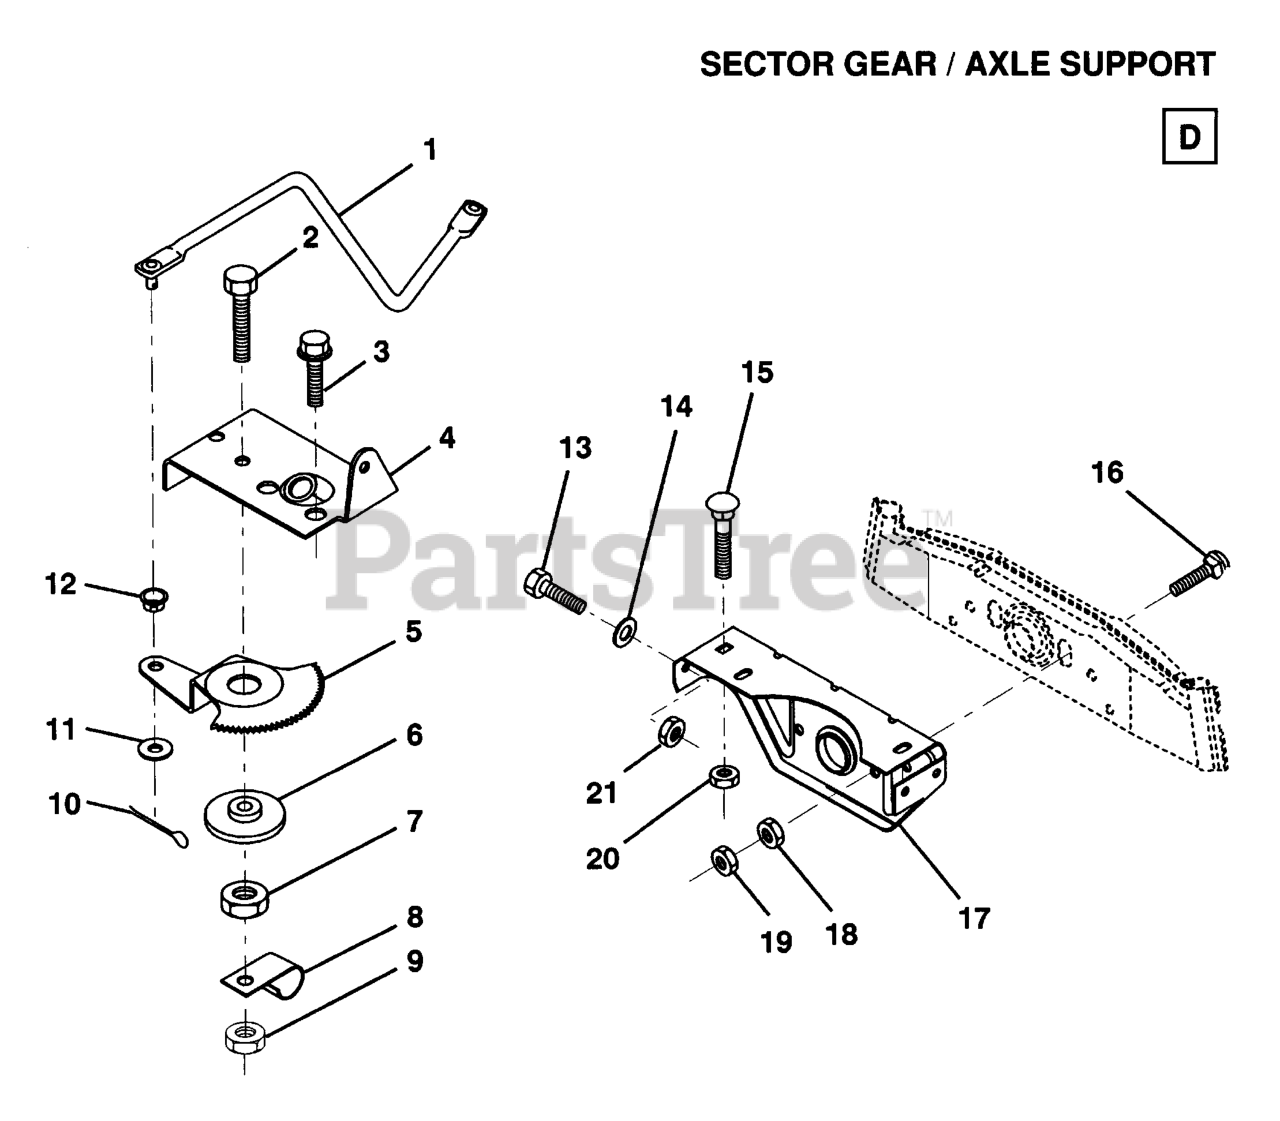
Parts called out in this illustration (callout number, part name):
1	LINK DRAG
3	Screw 5/16-18 x 1/2 Hex, Self Tapping 5/16-18 x 1/2
4	PLATE,STR SUPT
5	GEAR SECTOR
7	NUT LTV
8	CLIP INSULATOR
9	NUT LTV
10	PIN COTTER
11	WASHER
12	BUSHING.DRAGLINK (2 2)
13	BOLT
14	WASHER
15	BOLT D
16	BOLT
17	SUPT,FRT AXLE
19	LOCKNUT
21	LOCKNUT
